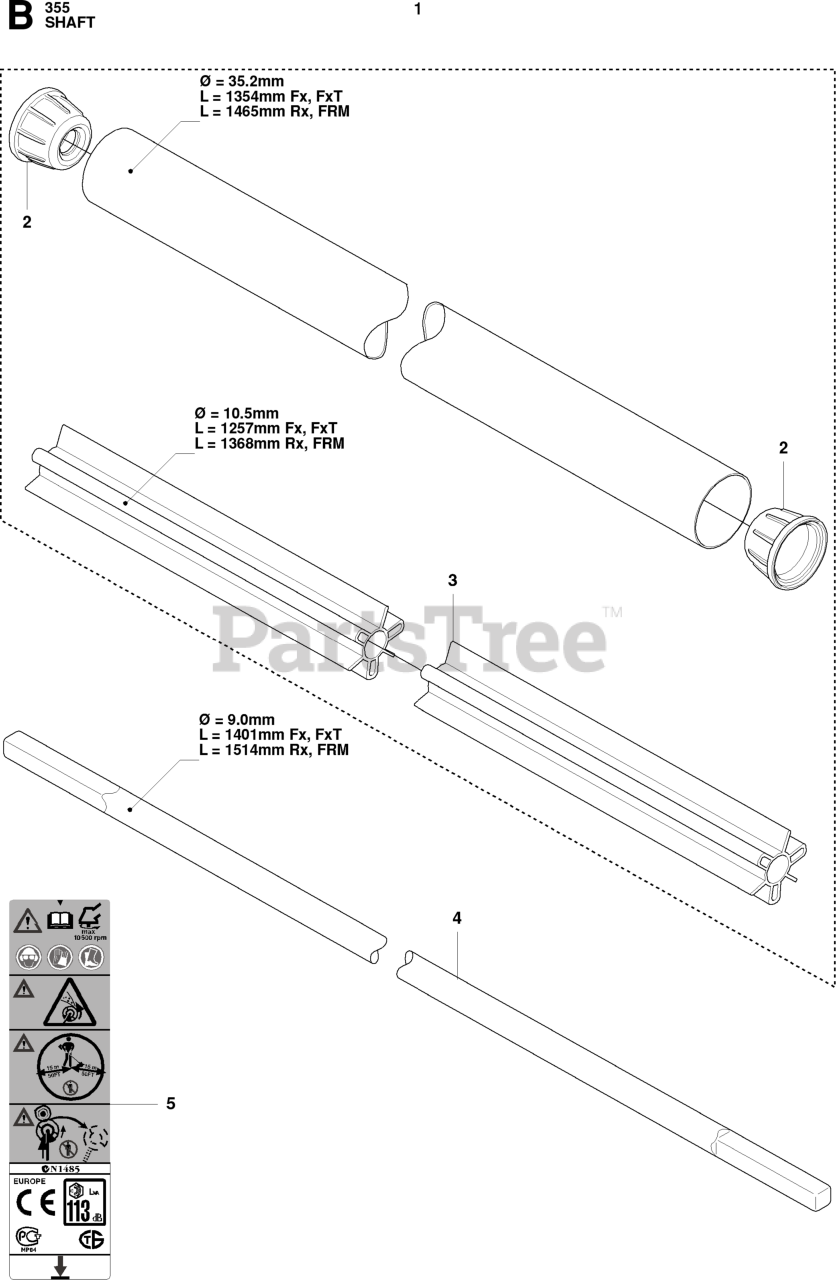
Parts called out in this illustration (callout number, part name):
1	TUBE ASSY
1	TUBE DRIVESHAFT ASSY FRM
1	TUBE DRIVESHAFT ASSY
2	RP SPACER
3	BEARING SHAFT
4	DRIVE SHAFT
